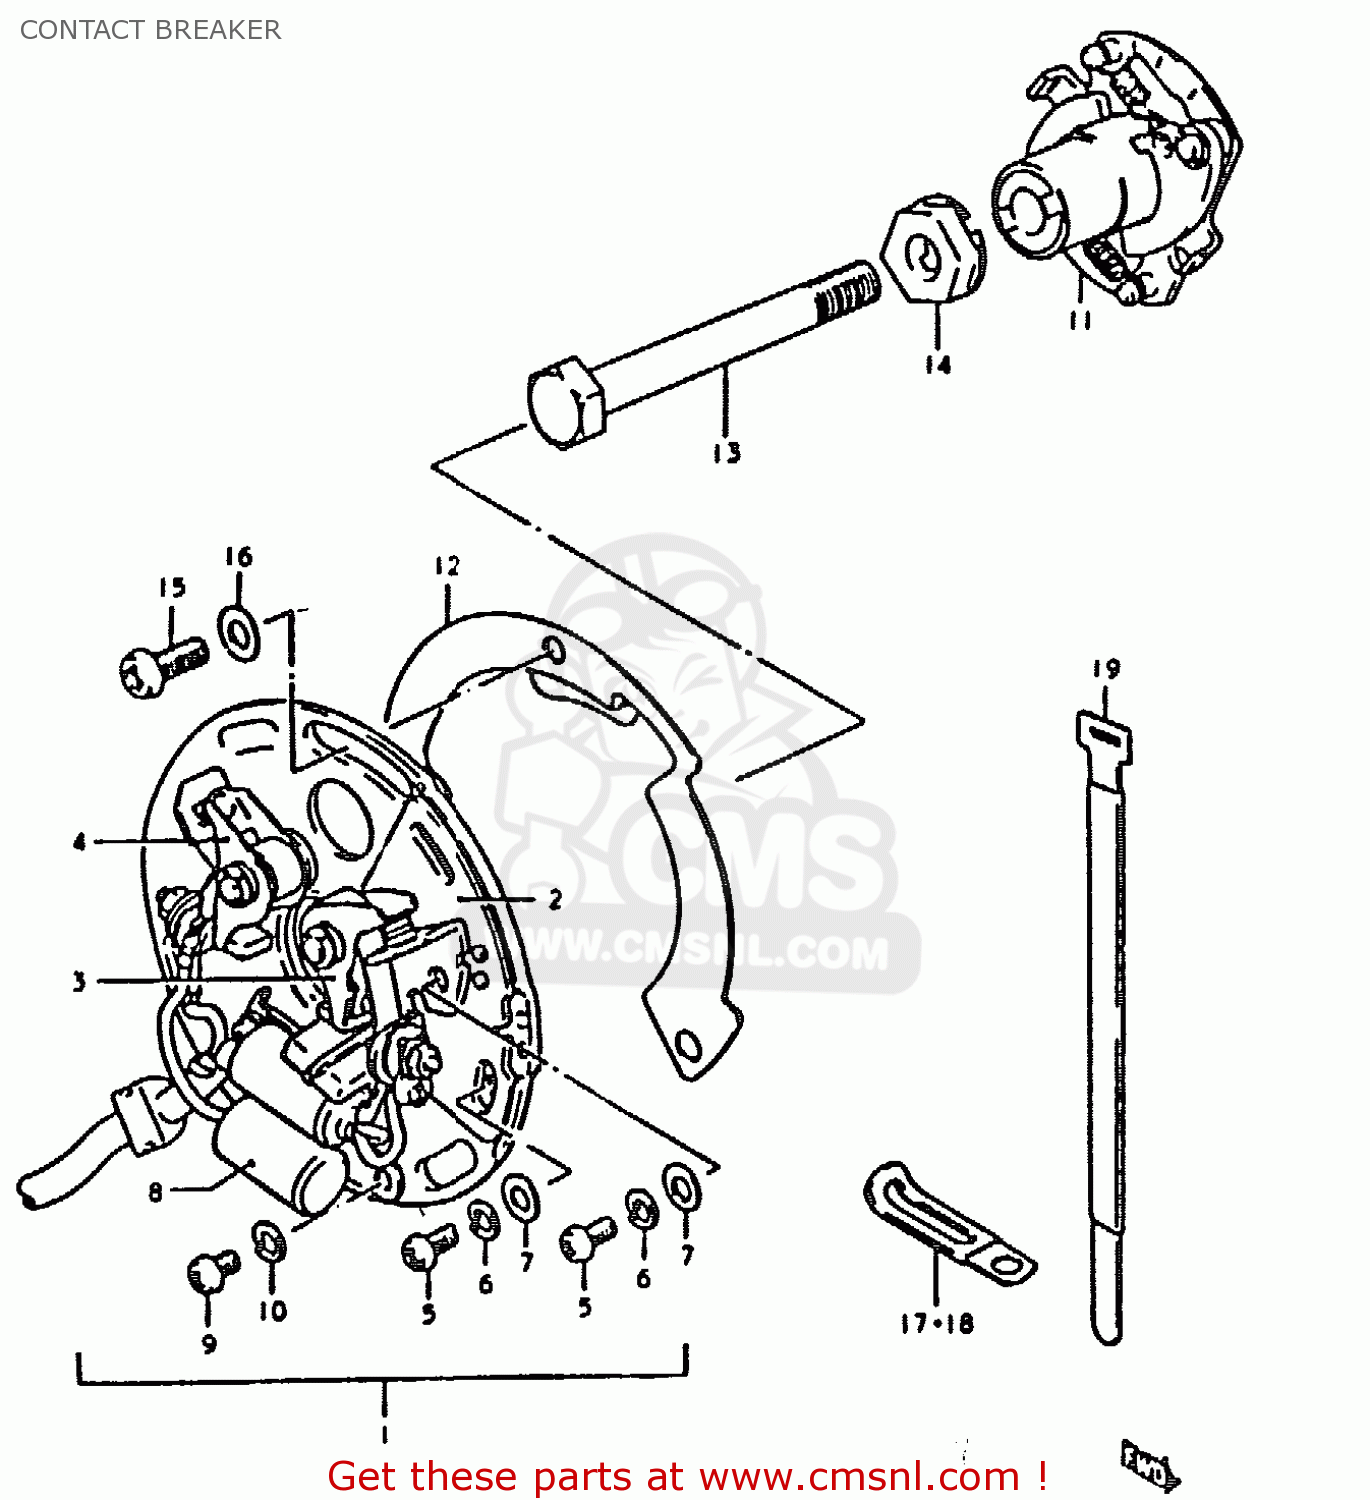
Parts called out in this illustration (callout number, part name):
1	BREAKER ASSEMBLY,CONTACT
2	PLATE,CONTACT POINT
3	POINT ASSY, CONTACT RH
4	POINT ASSY,L
5	SCREW
6	LOCK WASHER
7	WASHER
8	CONDENSER
9	SCREW
10	LOCK WASHER
11	GOVERNOR ASSEMBLY
12	PLATE,IGNITION TIMING
13	BOLT
14	WASHER
15	SCREW(5X12)
16	WASHER 5MM
17	CLAMP L:35
18	CLAMP
19	CLAMP
